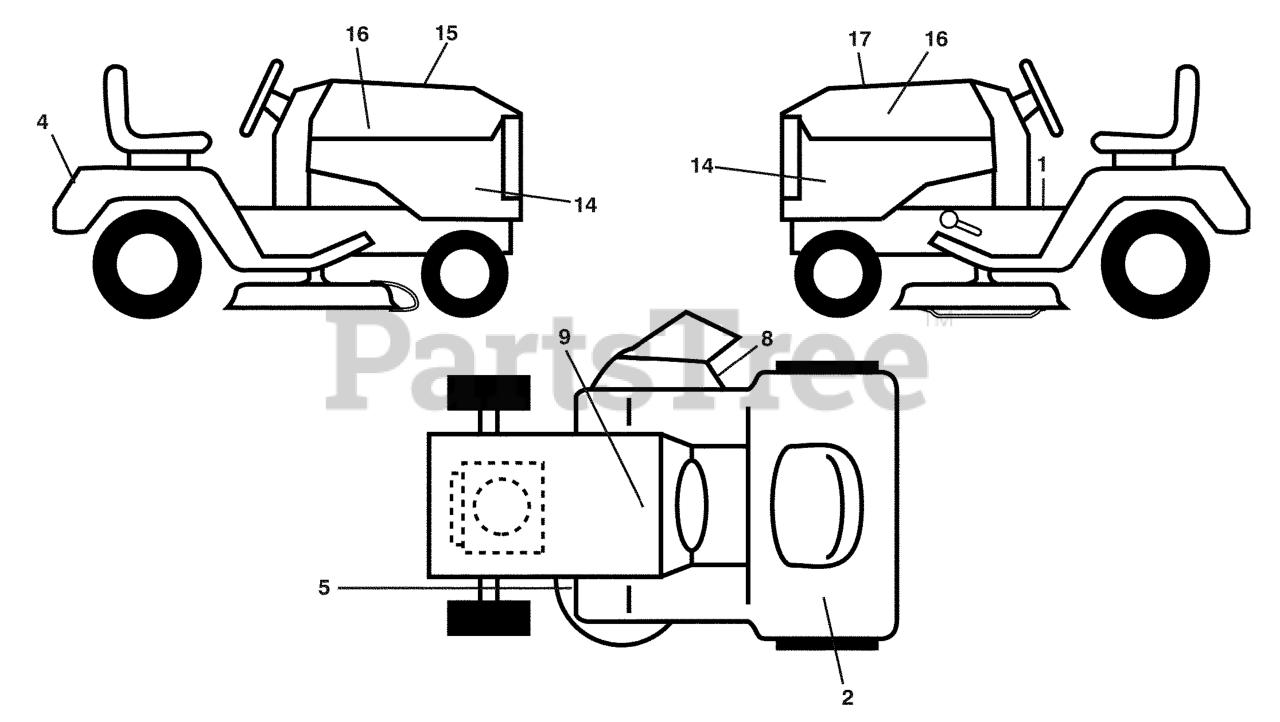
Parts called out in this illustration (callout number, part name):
1	DECAL.WARN.START.INSTRUCTIONS
2	DECAL,ETHANOL E85 WARNING
4	DECAL.FENDER
5	DECAL.MOWER
8	DECAL.MOWER.SCH.48/54
9	DECAL BTRY SYMBOLS
14	DECAL.PNL.SD.LGT2554.KOHL.
15	DECAL HOOD CUST. RESP.
16	DECAL.HOOD.LOGO.ORANGE.HUSQVAR
17	DECAL.RPL.SV730,
